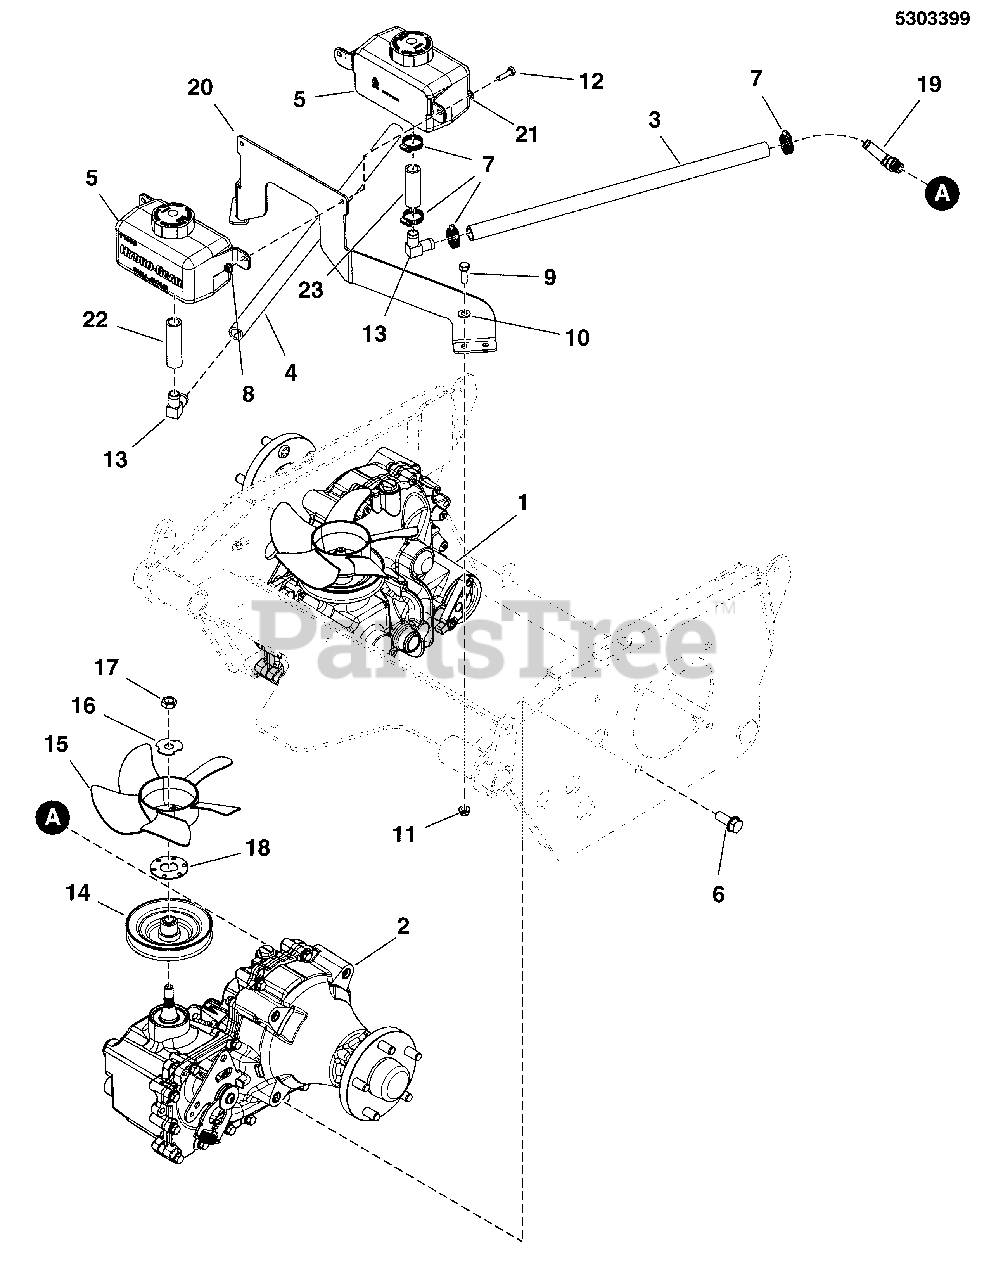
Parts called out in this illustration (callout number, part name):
1	ZT-5400, LONG AXLE, RH, 1015-1057R
2	ZT-5400, LONG AXLE, LH, 1015-1057L
3	HOSE, 5/8, PUSH-LOCK, 19.00
4	HOSE, 5/8, PUSH-LOCK, 22.00
5	HYDRO TANK, HYDRO-GEAR 71938, 1 LITER
6	BOLT, 1/2-13 X 1-1/4, SF, PLT W/PATCH
7	CLAMP, #10 HOSE, STAINLESS
8	NUT, 1/4-20 HEX NYLOCK FLANGE
9	BOLT, 5/16-18 X 1 GD5 YZ
10	WASHER, 5/16 SAE
11	NUT, 5/16-18 HEX NYLOCK FLANGE
12	BOLT, 1/4-20 X 1", GD
13	FITTING, 90 DEG, 5/8
14	PULLEY, ZT5400 (53179)
15	FAN, ZT5400
16	WASHER, ZT5400, SLOTTED
17	NUT, ZT5400
18	SPACER, ANTI ROTATE, ZT5400
19	FITTING, 45, 5/8 TUBE TO 7/8-14 O-RING
20	PLATE, TANK MOUNT - BLK
21	WASHER, 1/4 SAE
22	HOSE, 5/8, PUSH-LOCK, 3.00
23	HOSE, 5/8, PUSH-LOCK, 2.50
